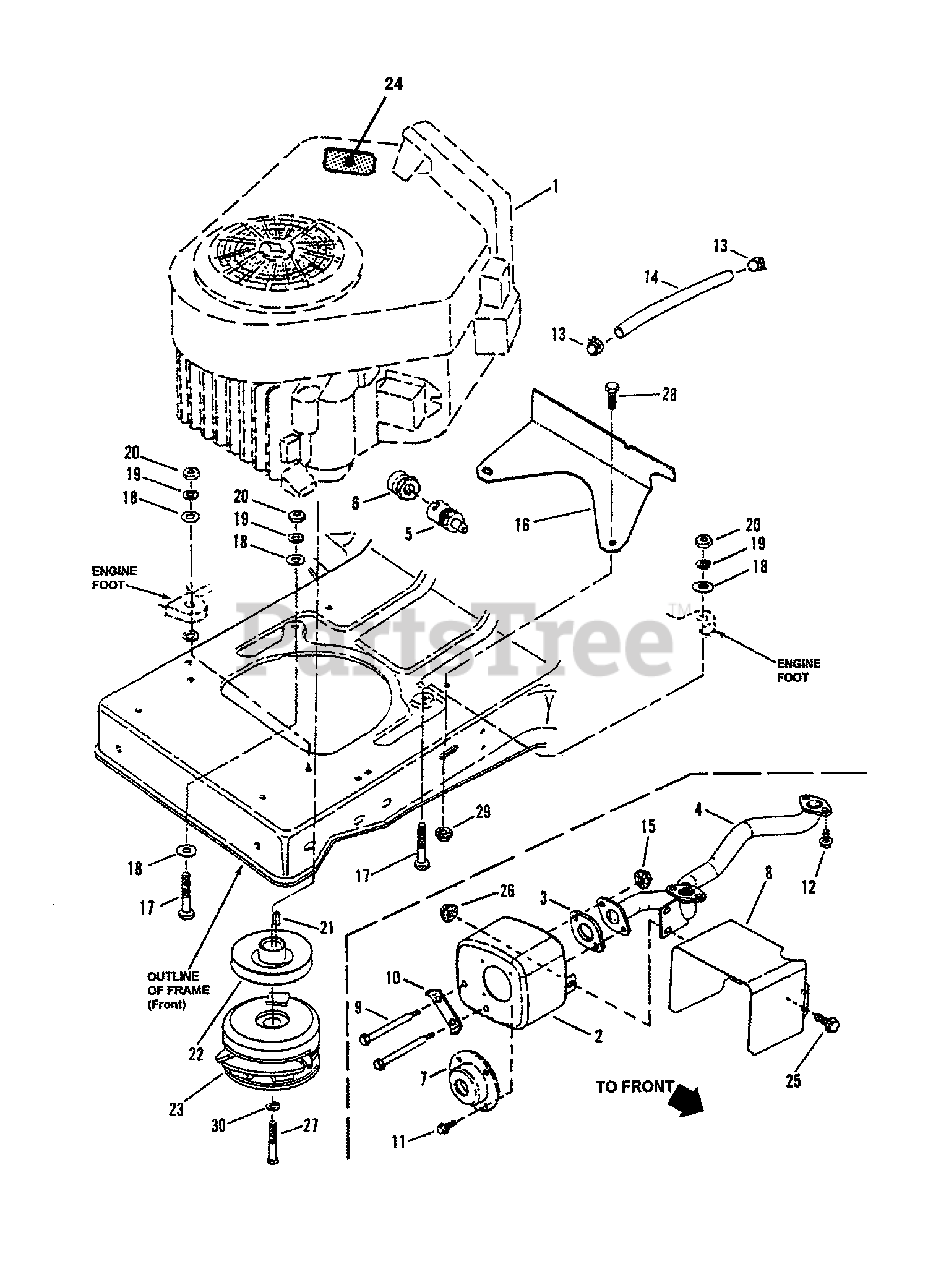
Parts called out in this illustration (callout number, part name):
2	MUFFLER, 16HP B&S
3	GASKET, Exhaust
4	MANIFOLD, Exhaust
5	ASSEMBLY, Oil Valve
6	EXTENSION, Oil Drain
7	DEFLECTOR, Exhaust (Direct Out)
8	SHIELD, Muffler Heat
9	SHOULDER BOLT, 5/16-18 thread x 4"
10	SCREW LOCK
11	SCREW, #8-18 x 1/2" Hex Head Sheet Metal
12	SCREW, 5/16-18 x 1/2" Hex Washer Self-Tap
13	CLAMP, .490 x .31
14	FUEL LINE, 14" long
15	NUT, 5/16-18 Hex Flange Lock, GR5
16	SHIELD, Heat
17	SCREW, 5/16-18 x 1-3/4" Hex Head Cap, GR5
18	WASHER, 5/16" Flat
19	WASHER, 5/16" Split Lock
20	NUT, 5/16-18 Hex, GR5 or B
21	KEY, 1/4 Square x 3/4"
22	PULLEY, Traction Drive
23	CLUTCH/BRAKE
24	DECAL, Warning-Speed Setting 14, 16, & 18 HP ENGINES
25	SCREW, 1/4-20 x 5/8" Hex Head Cap, GR5
26	NUT, 1/4-20 Hex Flange Lock
27	SCREW, 7/16-20 x 2-1/2" (Special), GR5
28	SCREW, 5/16-18 x 1" Hex Head Cap, GR2
29	NUT, 5/16-18 Hex Flange Lock, GR5
30	WASHER, 7/16" Split Lock
